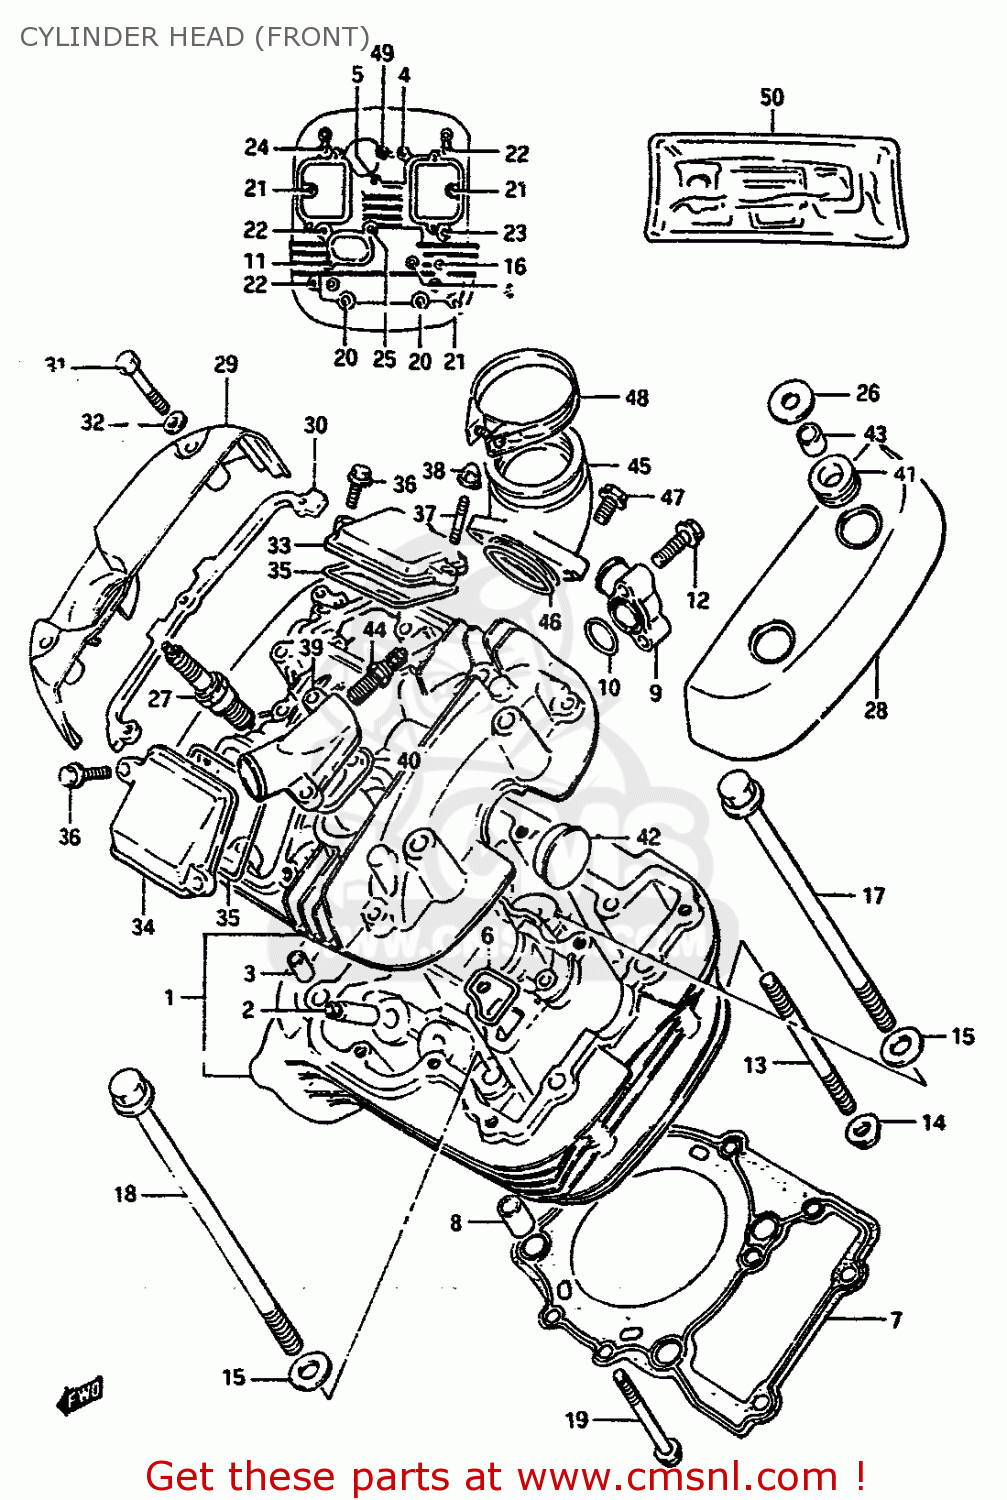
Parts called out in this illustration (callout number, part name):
1	HEAD ASSEMBLY,CYLINDER,FRONT
2	GUIDE,VALVE
3	PIN(11X14)
4	BOLT(6X50)
5	BOLT(6X55)
6	GASKET,CYLINDER HEAD WATER (NAS)
7	GASKET,CYLINDER HEAD FR (MCA)
8	PIN
9	UNION,CYLINDER HEAD WATER
10	O RING(D:2.4,ID:17.8)
11	BOLT 6X20
12	BOLT
13	BOLT,STUD
14	NUT
15	WASHER(10.5X22X2.3)
16	BOLT(8X140)
17	BOLT(10X155)
18	BOLT(10X165)
19	BOLT
20	BOLT(8X245)
21	BOLT 6X25
22	BOLT
23	BOLT
24	BOLT
25	BOLT(6X55)
26	WASHER (8.2X24X1.6)
27	PLUG,SPARK(DPR8EA-9)
28	CAP,CYLINDER HEAD COVER FR,L
29	CAP,CYLINDER HEAD COVER FR,R
30	CUSHION,FR,R CAP
31	BOLT
32	WASHER
33	CAP,INSPECTION
34	CAP,INSPECTION,EXHAUST
35	GASKET,INSPECTION CAP (NAS)
36	BOLT
37	STUD 6X16
38	NUT
39	UNION
40	GASKET,WATER OUTLET UNION (NAS)
41	CUSHION
42	PLUG
43	BUSH
44	GAUGE ASSY,WATER TEMP
45	PIPE,INTAKE
46	O-RING (D:2.4 ID:39.7)
47	BOLT
48	CLAMP,PIPE
49	BOLT
50	GASKET SET
